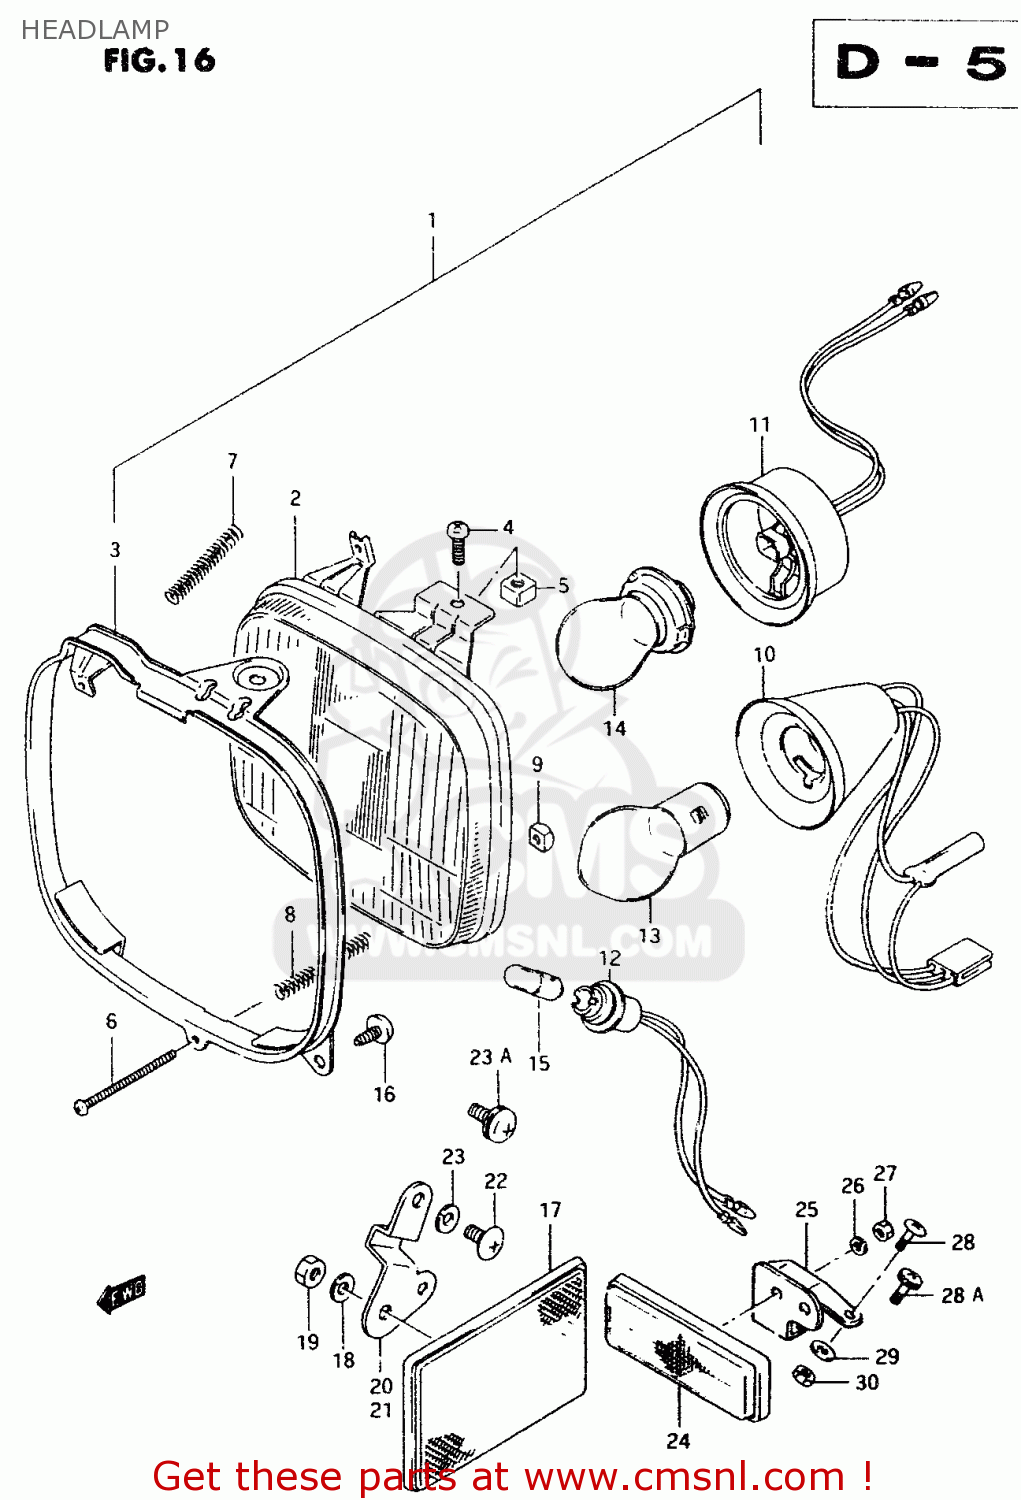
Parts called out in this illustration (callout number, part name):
1	HEADLAMP ASSY
2	UNIT
3	RING,MOUNTING
4	SCREW 5X12
5	NUT
6	SCREW,HEADLAMP ADJUST
7	SPRING
8	SPRING
9	NUT
10	SOCKET
11	SOCKET,HEAD LAMP
12	SOCKET,PARKING
13	BULB(12V35/35W)
14	BULB(12V15W)
15	BULB(12V4W)
16	SCREW
17	REFLEX REFLECTOR
18	WASHER,LOCK
19	NUT
20	BRACKET, RH
21	BRACKET, LH
22	SCREW 5X10
23	WASHER,LOCK
23A	SCREW
24	REFLECTOR, FRONT
25	BRACKET, FRONT REFLECTOR
26	LOCK WASHER
27	NUT
28	SCREW
28A	SCREW
29	WASHER
30	NUT
